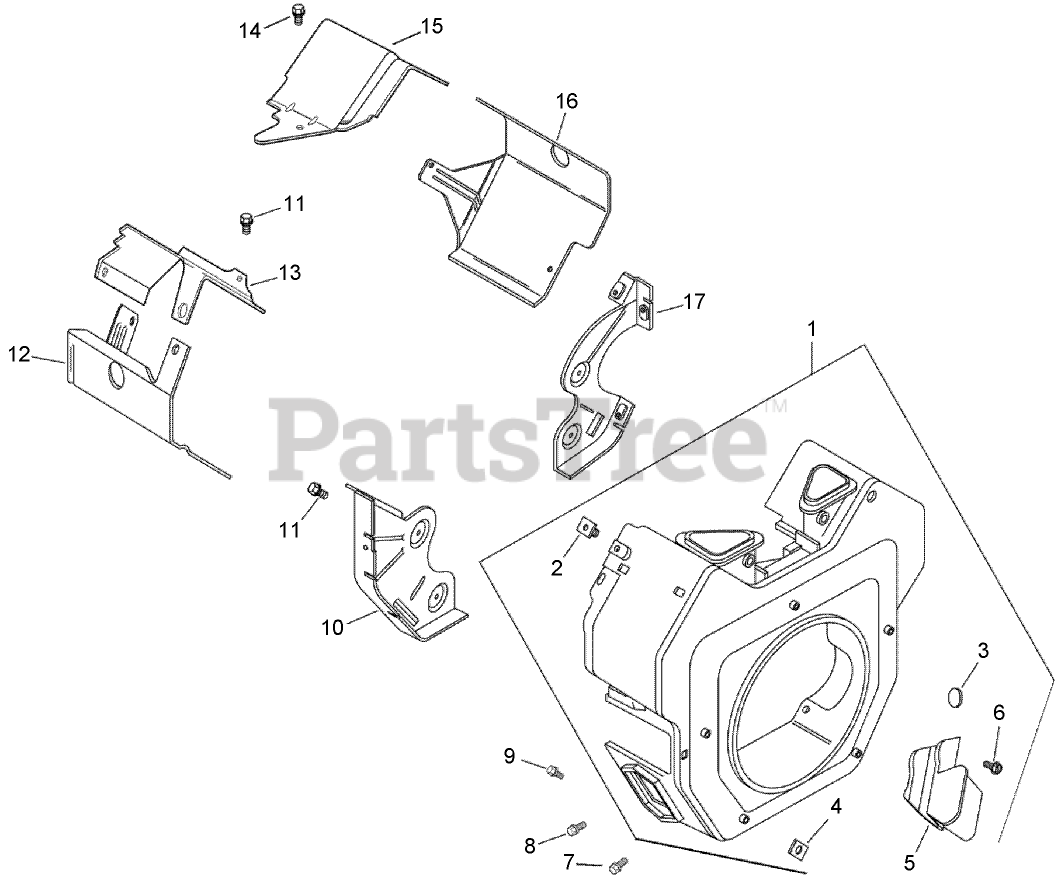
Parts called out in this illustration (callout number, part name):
1	Blower Housing ASM (Includes 2-6)
2	Nut-Plastic
3	PLUG-BUTTON (9/16)
4	NUT-PLASTIC
5	Cover-Housing, Blower
6	Screw-WSH HD Tap (8-18X.50)
7	Screw-Hex Flange, Heavy (M5x0.8x16)
8	SCREW-FLANGE, THREAD FORMING (M5X0.8X16)
9	SCREW-FLANGE, THREAD FORMING (M5X.8X20)
10	Plate-Backing (No. 2 Side)
11	SCREW-FLANGE, THREAD FORMING (M6X1.0X16)
12	Baffle-Barrel, Cylinder (No. 2 Side)
13	BAFFLE-VALLEY (No. 2 SIDE)
14	SCREW-HHFTF (M5X.80X10)
15	BAFFLE-VALLEY (No. 1 SIDE)
16	Baffle-Barrel, Cylinder (No. 1 Side)
17	Plate-Backing (No. 1 Side)
